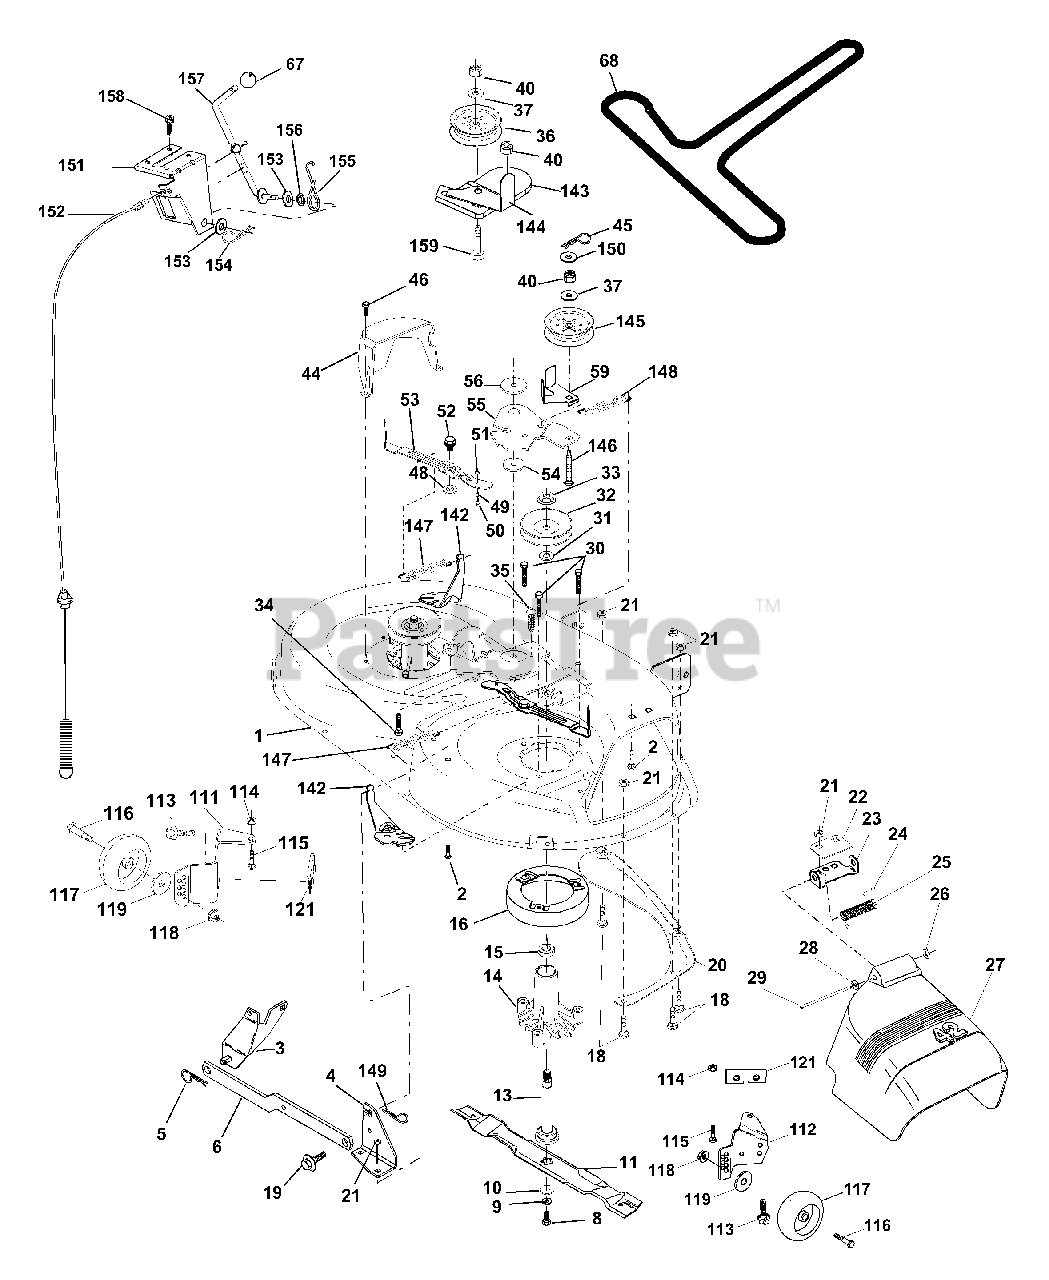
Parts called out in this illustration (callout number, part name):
1	Deck Asm MWR 42"weldment
2	Bolt Rdhd Sqnk 5/16-18unc X3/4
3	Bracket Asm Fr Sway Bar 38/42
4	Bracket Asm Deck 42"sway Bar
5	Retainer Spring
6	Arm Suspension Rear
8	Bolt 3/8 - 24 X 1.25 Gr 8
9	Washer Lock Hvy 3/8
10	Washer Hard Blade Mower Vented
11	Blade Mower 42"
13	Shaft Asm W/lower Bearing
14	Housing Mandrel Vented
15	Bearing Ball Mandrel
16	Stripper Mower Vented
18	Bolt Rdhd Sqnk 5/16-18 X 5/8
19	Bolt Shoulder
20	Baffle Vortex 42
21	Nut
22	Stiffener Bracket 42"deck
23	Bracket Deflector Mower 42"
24	Cap Sleeve 80x 112 Blk Mower
25	Spring Torsion Deflector 2 52
26	Nut Push Phos & Oil
27	Shield Deflector Mower 42" Blk
28	Washer 11/32 X 5/8 X 16 Ga
29	Rod Hinge 42"6 75 Wlg
30	Screw Thd Rolling Washer Head
31	Washer Spacer Mower Vented
32	Pulley Mandrel 42"
33	Nut 9/16 Toplock Flng Oil Dip
34	Bolt Rdhd 3/8-16uncx1-3/4 Gr5
35	Fastner Christmas Tree
36	Pulley Idler Flat 3 060
37	Washer 13/32 X 13/16 X 16
40	Nut Crownlock 3/8-16 UNC
44	Guard Mandrel LH Black
45	Spring Retainer 1" Zinc/cad
46	Screw Hex Thd Cut 1/4-20x5/8 T
48	Washer Hardened Smaller
49	Roller Asm Cam Follower 42"dec
50	Bolt Shldr 10-24 Zinc Gr 5 42"
51	Nut Lock #10-24 Unc
52	Bolt Shoulder 5/16-18 Unc Blkz
53	Arm Asm Pad Brake
54	Washer Hardened
55	Arm Idler 42"mower LT/YT
56	Spacer Retainer Mower
59	Guard TUV Idler
67	Knob Rd 3/8-16 Plstc Thds Blk
68	V-Belt Mower 42"
111	Bracket Wheel Gauge LH 42" Deck
112	Bracket Gauge Wheel RH 42" Deck
113	Screw Tapping 5/16-18 Unc
114	Nut Keps 5/16-18 UNC
115	Bolt Carriage 5/16-UNC x 1/2
116	Bolt Shoulder
117	Wheel Gauge
118	Nut Centerlock 3/8-16 UNC
119	Washer 3/8 x 7/8 x 14 Ga.
121	Bracket Extruded Guage Wheel
142	Arm Spring Brake Mower
143	Bracket Arm Idler 42"
144	Keeper Belt 42" Clutch
145	Pulley Idler Flat
146	Bolt Carriage Idler
147	Spring Extension
148	Spring Return Idler
149	Retainer Spring Yellow
150	Washer 9/32 x 3/4 x 16 Ga.
151	Bracket Clutch Cable
152	Clutch Cable 42"
153	Washer Flat 3/8" Type B
154	Spring Retainer
155	Spring Retention Lvr Cltch Cab
156	Spacer Clutch Cable
157	Rod Clutch Cable 3/8"
158	Screw Hex Thd Cut 1/4-20 x 5/8
159	Bolt Rdhd Sqn 3/8-16 Unc x 1-3/4
